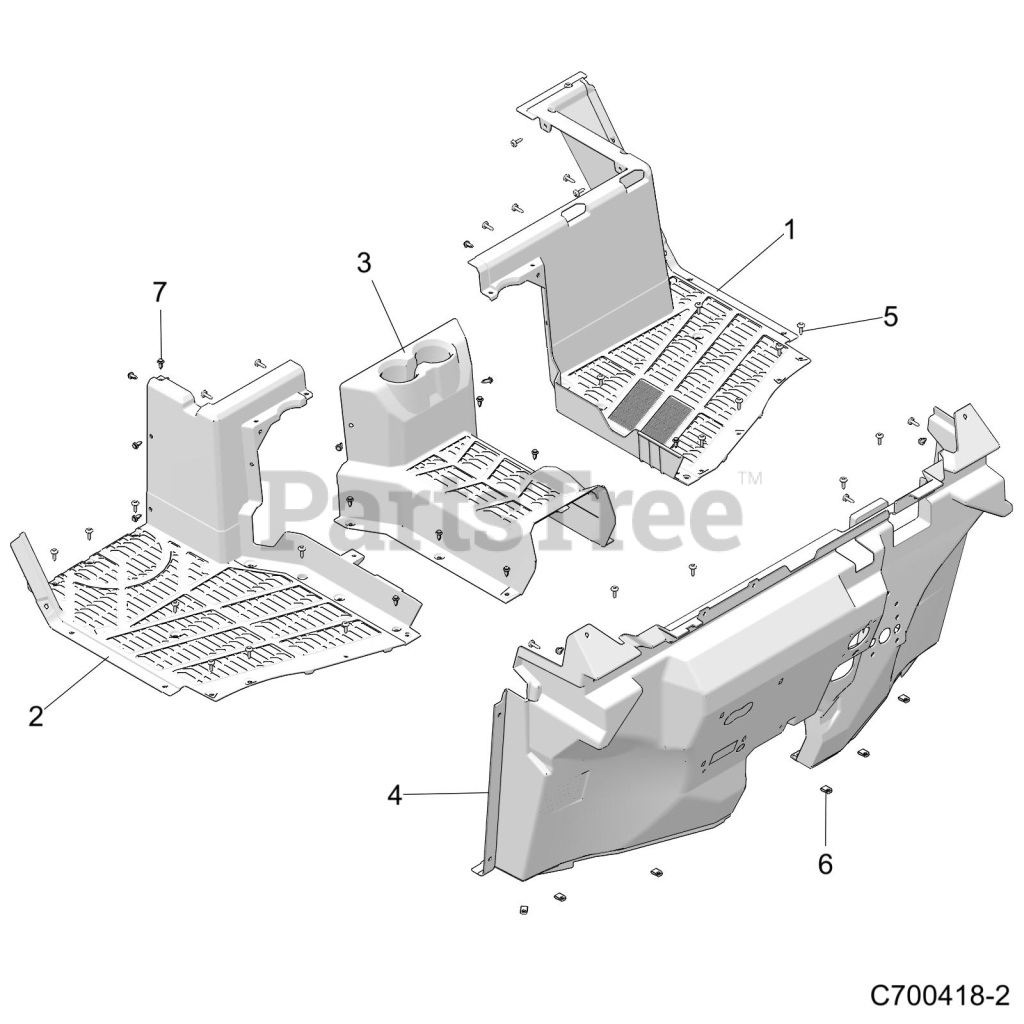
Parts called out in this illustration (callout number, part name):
1	FLOOR,LH,BLK
2	FLOOR,RH,BLK
3	COVER-TUNNEL FLOOR,BLK
4	FLOOR-CLOSEOFF,UPPER,SPLY,BLK
5	SCR-TXTH-M6X1.0X25 RIE
6	NUT-M6-1.0,U-TYPE (2.5-3.8)
7	RIVET-TUFLOK,.315-.325X.787 (5
